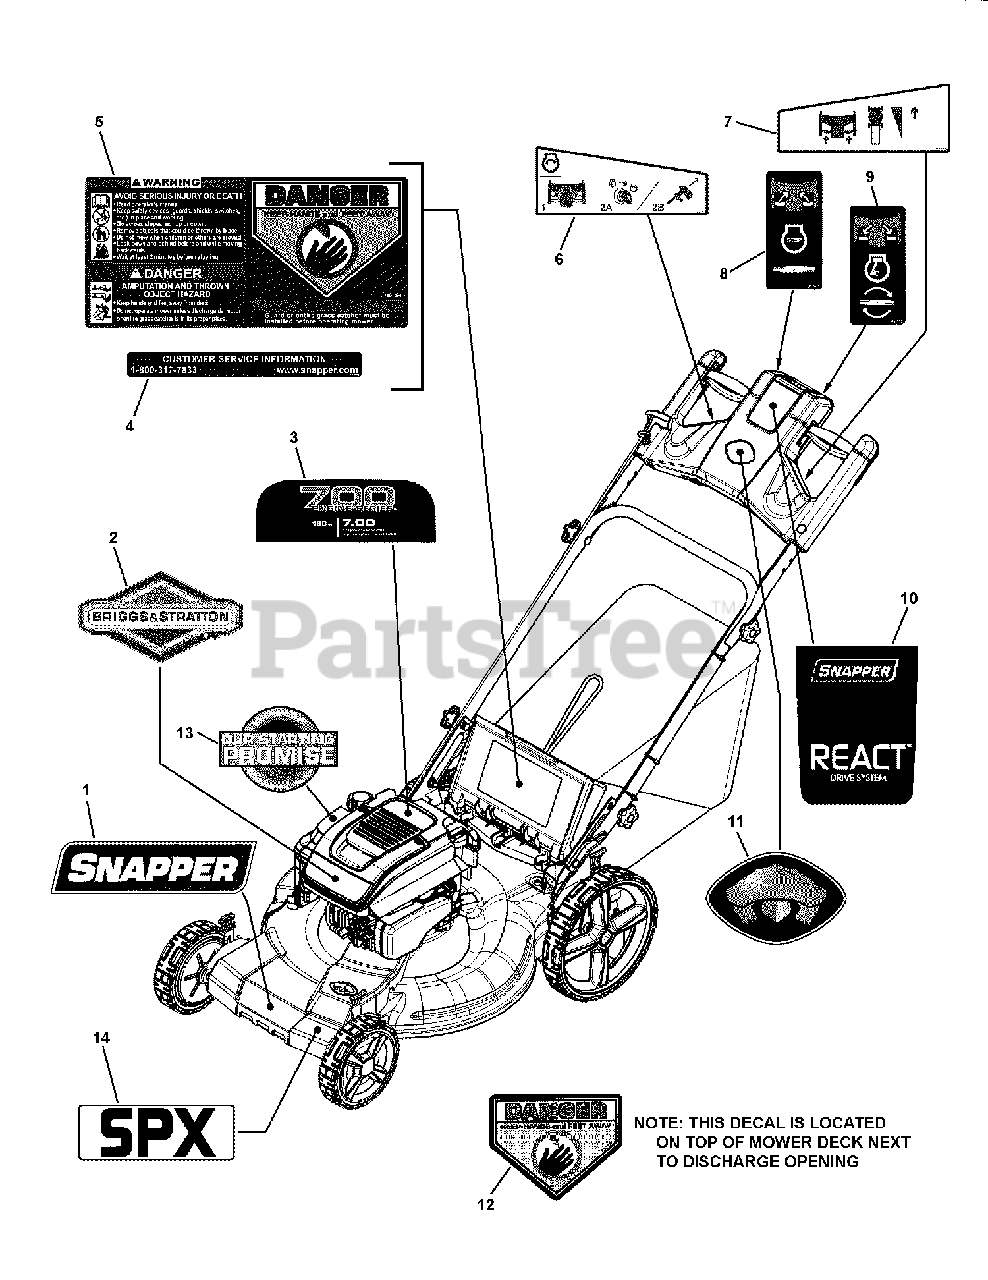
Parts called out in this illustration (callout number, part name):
1	DECAL, Front Shroud, Snapper Logo
2	* DECAL, Briggs Engine, SNAPPER
3	DECAL, Briggs Engine, 700 Series
4	DECAL, Customer Service, MY08, Snapper
5	DECAL, Warning, Rear Discharge Door
6	DECAL, Start, React
7	DECAL, Drive, React
8	DECAL, Stop, React
9	DECAL, Run, React
10	DECAL, Handle, React Drive
11	DECAL, Handle, Domed Turtle
12	DECAL, DANGER, Cut Finger
13	LABEL, Starting Promise
14	DECAL, Front Cover, SPX Series
